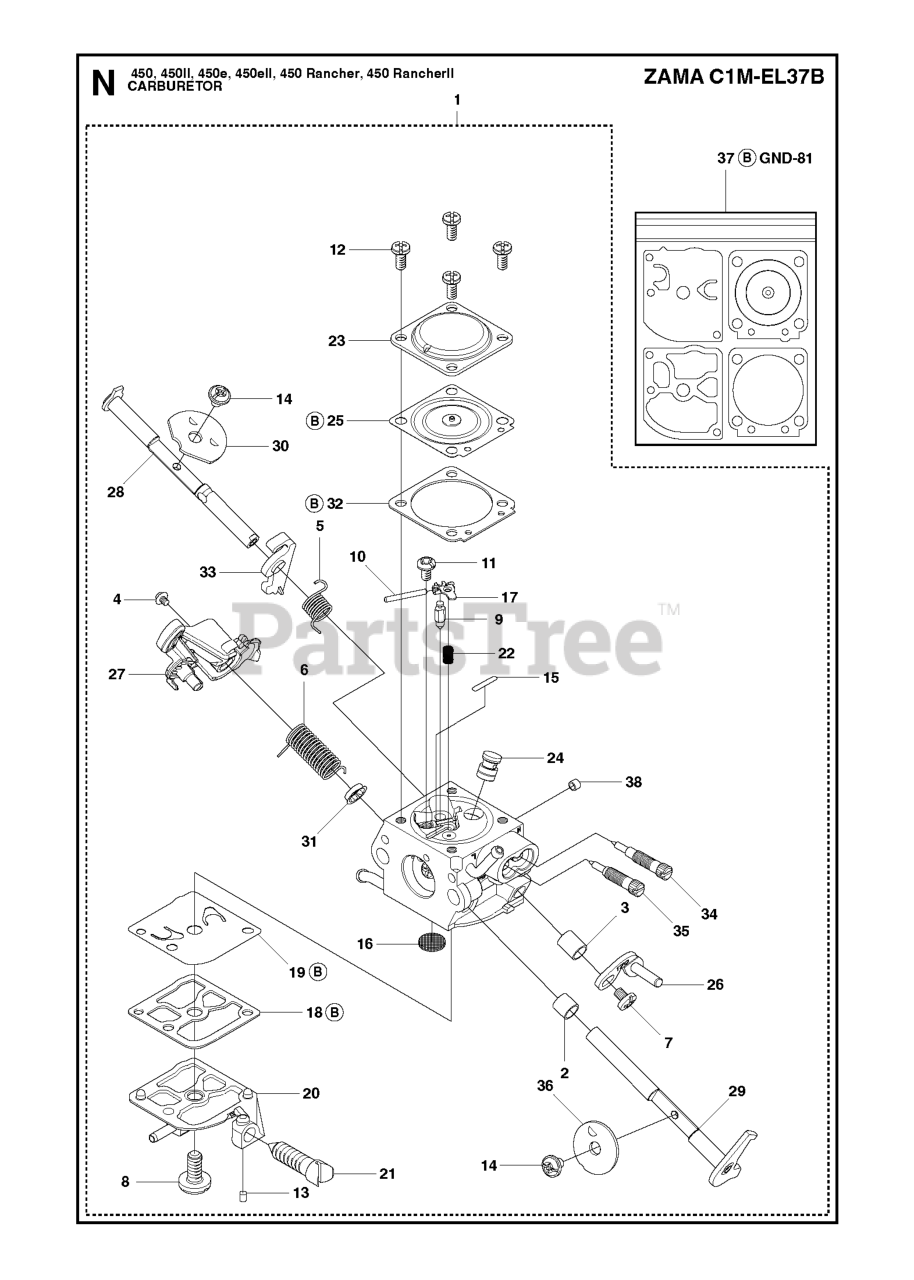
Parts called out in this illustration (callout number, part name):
1	CARBURETOR
9	INLET NEEDLE
10	PIN RETAINING SCREW
19	PUMP DIAPHRAGM
27	THROTTLE LEVER
28	SHAFT ASSY
29	SHAFT ASSY
30	CHOKE VALVE
37	GASKET KIT
